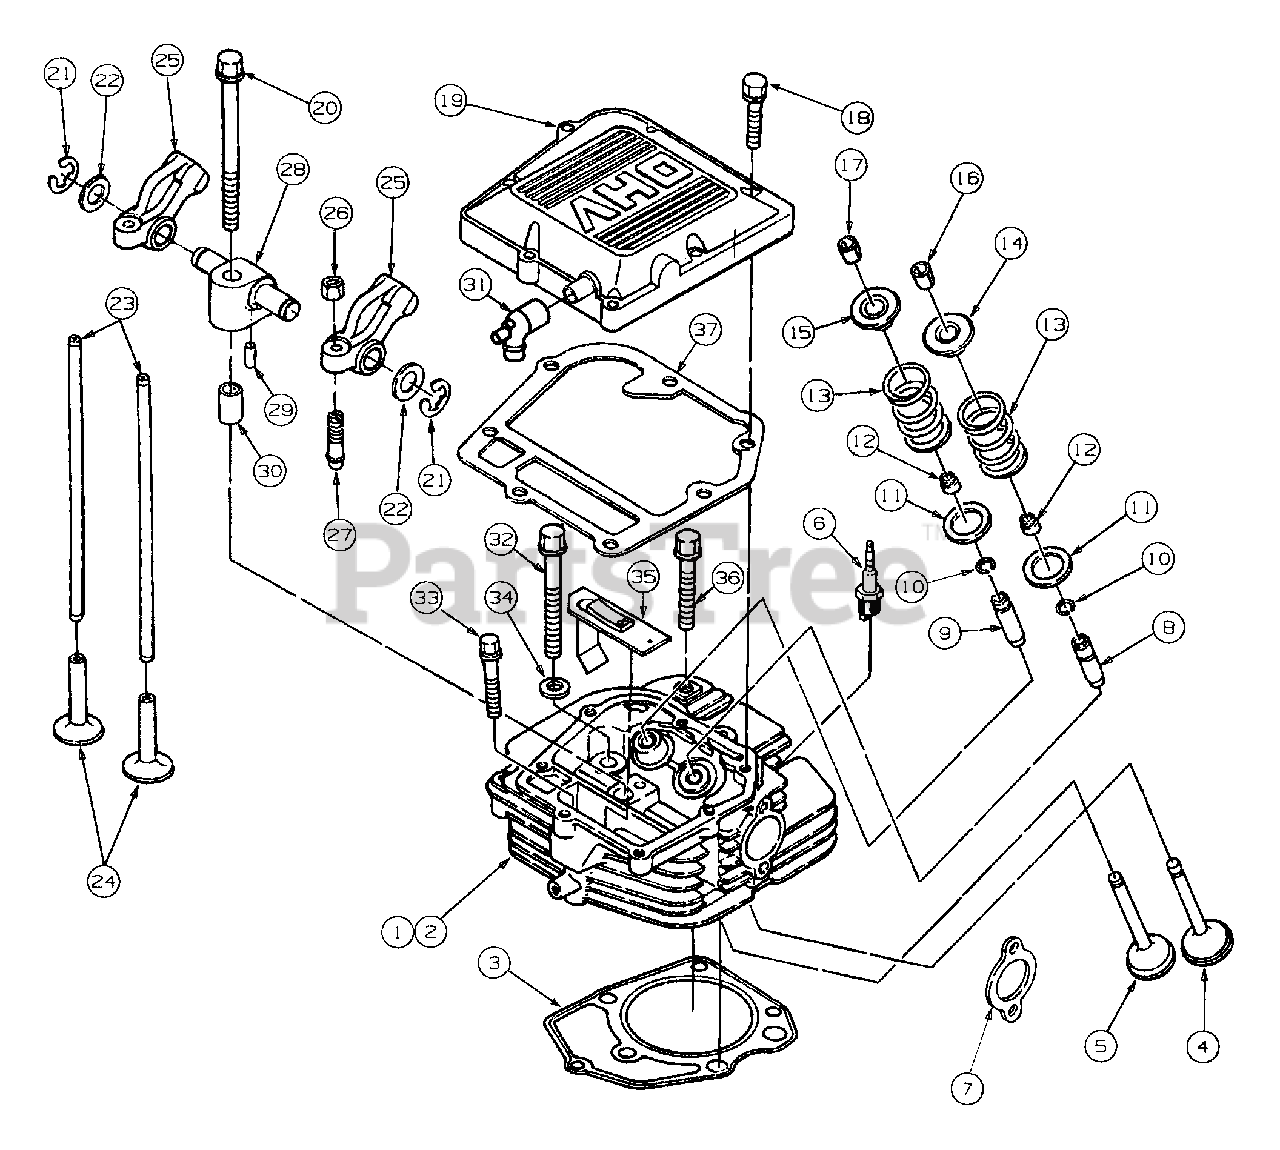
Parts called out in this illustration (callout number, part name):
1	Head Assy, Cyl
2	Head, Cylinder
3	Gasket, Cylinder Head
4	Valve, Intake
5	Valve, Exhaust
6	Spark Plug
7	Gasket, Exhaust
8	Guide, Intake Valve
9	Guide, Exhaust Valve
10	Ring, Valve Guide
11	Washer, Valve Spring
12	Seal, Intake Valve Stem
13	Spring, Valve
14	Retainer, Intake Valve Spring
15	Retainer, Exhaust Valve Spring
16	Lock, Intake Valve
17	Lock, Exhaust Valve
18	Screw Hex Flange M6 x 1 x 25
20	Bolt, Cyl. Head, M10 x 1.5 x 125
21	Clip, Retainer
22	Washer, Rocker Arm
25	Arm Assy, Rocker
26	Nut, Lash Adjusting, M7 x .75
27	Screw, Lash Adj, M7 x .75 x 18
28	Shaft, Rocker Arm
30	Pin, Hollow Dowel
31	Connector, Breather Tube
32	Bolt, Cyl Head, M10 x 1.5 x 86
33	Bolt, Cyl Head, M8 x 1.25 x 50
34	Washer, Flat, M10
36	Bolt, Cyl Head, M10 x 1.5 x 66
37	Gasket Valve Cover
